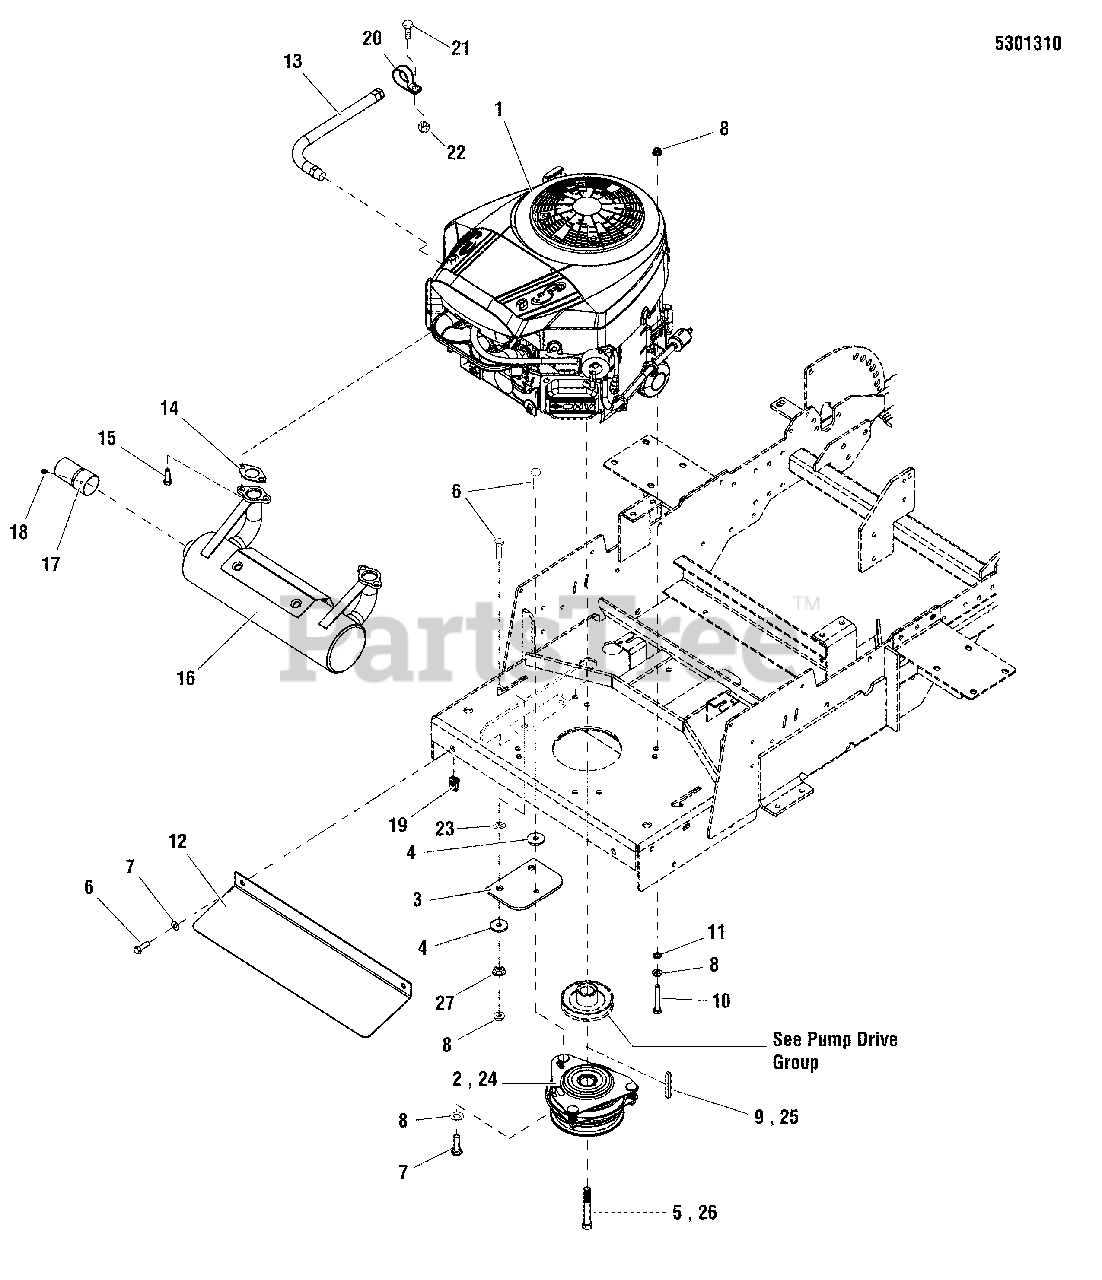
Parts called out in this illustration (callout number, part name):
1	* ENGINE, 26HP ELS BRIGGS, Mod. 44P777-0133-G1
2	CLUTCH, ELECTRIC, OGURA GT2.5, NZM
3	CLUTCH ANCHOR PAD
4	WASHER, .34 X 1.25 X 10 GA
5	BOLT, CRANKSHAFT, 7/16X2-3/4, PATCH YZ
6	BOLT, 5/16-18 X 1 GD5 YZ
7	WASHER, 5/16" SAE
8	NUT, 5/16-18 HEX NYLOCK FLANGE
9	KEY, 1/4" SQ. X 3.00
10	BOLT, 5/16-18 X 2-1/4" GD5 YZ
11	WASHER, 5/16" INT. TOOTH LOCK
12	PLATE, HEAT SHIELD - RED
13	HOSE, OIL DRAIN
14	GASKET, EXHAUST
16	MUFFLER, B&S-ELS 22-26HP
17	EXTENSION, TAILPIPE, 3"
18	SCREW
19	BODY CLIP, 5/16-18 X 1/2 DEEP
20	CLAMP, VINYL INSULATED
21	BOLT, 1/4-20 X 3/4 GD5 YZ
22	NUT, 1/4-20 HEX NYLON FLANGE
23	5/16" PUSH-ON NUT RETAINER, STL, CZ
24	CLUTCH, WARNER ELECTRIC, I-5219-104
25	KEY, 1/4 SQ. X 1.00
26	BOLT, 5/16-18 X 2 GD5 TFL
27	NUT, 5/16-18 HEX SERRATED FLANGE (LARGE)
